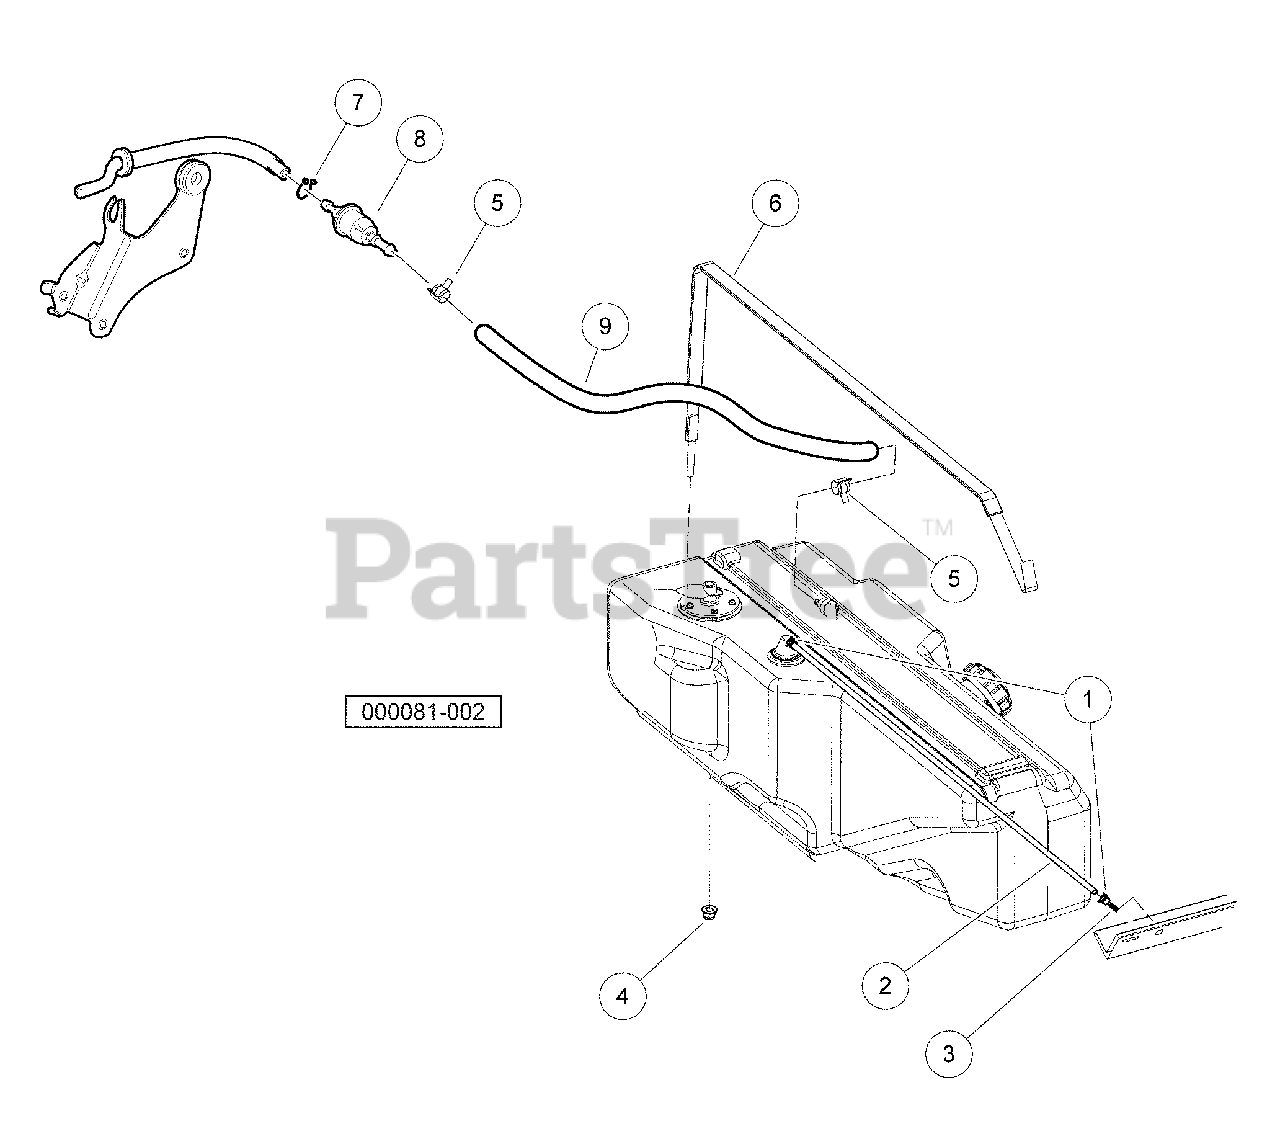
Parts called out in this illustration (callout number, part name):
1	Clamp, 0.301 ID Hose
2	Hose, Fuel, Vent, 22" Long
4	Nut,m8,all Metal Lock
5	Clamp, Hose, Ctb 13mm
6	Strap, Tank, Fuel
7	Clip, Tube, B10
8	Filter, Fuel
9	Hose, Tank To Filter, Fh680d
